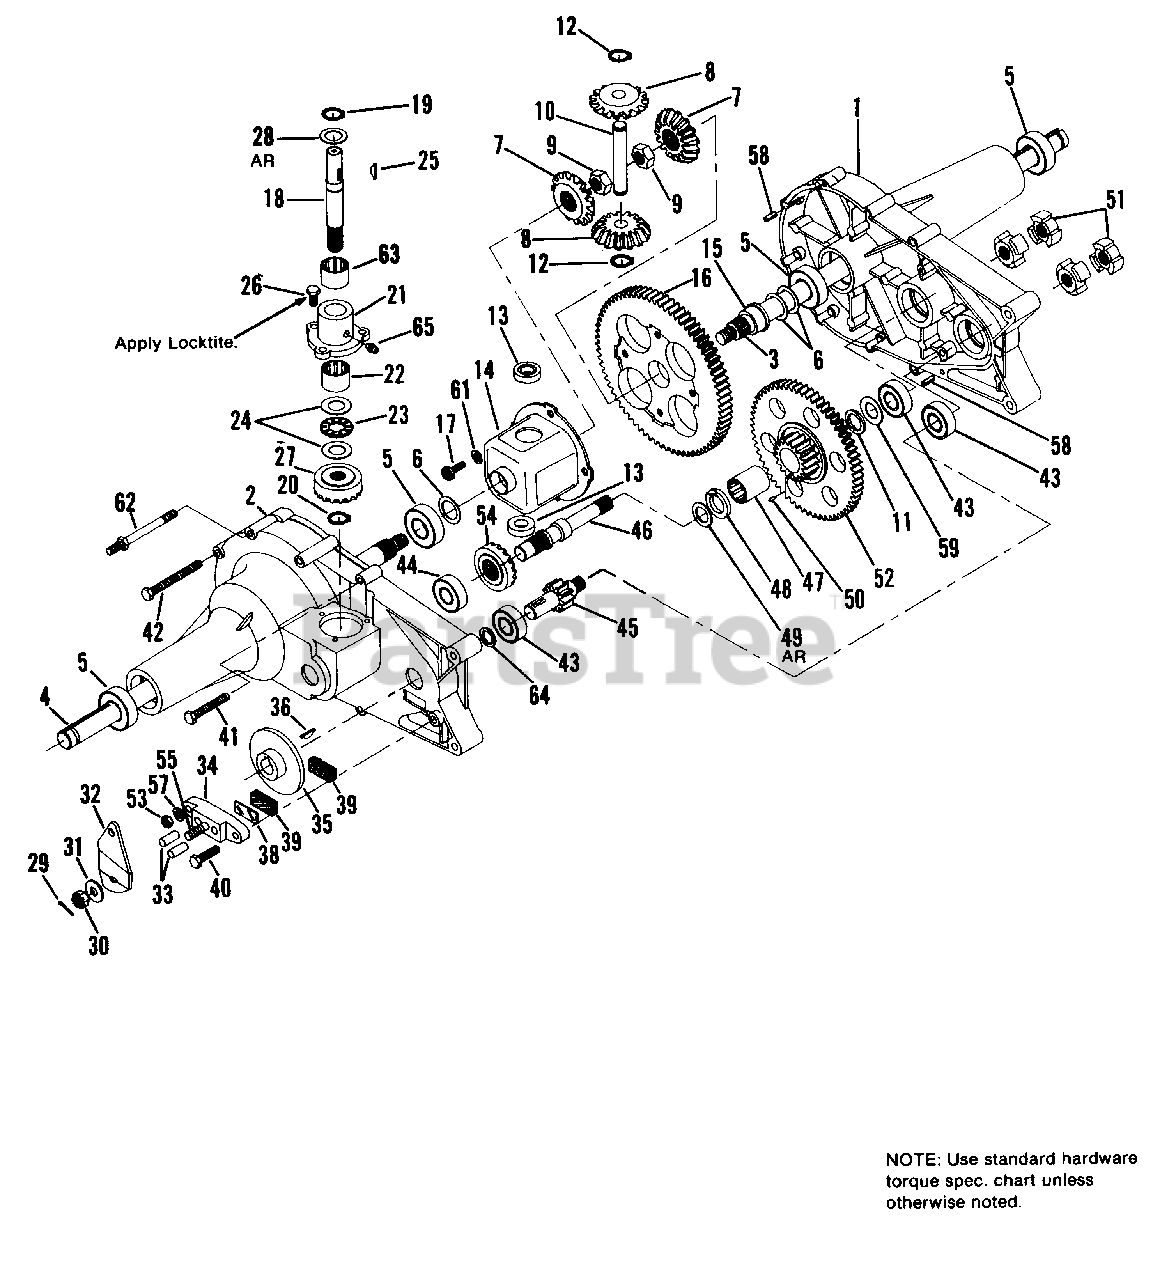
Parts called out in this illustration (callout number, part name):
1	HOUSING, Half, L.H.
2	HOUSING, Half, R.H.
3	AXLE, L.H., 3/4"
4	AXLE, R.H., 3/4"
5	BEARING, Ball
6	WASHER, Flat, 3/4 I.D. x 1-1/8 O.D. x .030 Thk.
7	GEAR, Miter
8	GEAR, Miter
9	NUT, Hex Jam w/Patch, 1/2-20
10	SHAFT, Cross
11	GREASE, Seal, Bronze
13	BEARING, Thrust
14	HOUSING ASSY., Differential
15	BEARING, Flange
16	GEAR, Differential 1/2 Tooth
17	BOLT, Torx Hd., 1/4-29 x 5/8" Lg.
18	SHAFT, Input
20	RETAINING RING, 7/16" Dia. Ext.
21	HOUSING, Input Bearing
22	BEARING, Needle
23	BEARING, Thrust
24	WASHER, Flat, 5/8 I.D. x 1-1/8 O.D. x .030 Thk.
25	KEY, Hi-Pro, 1/8 x 5/8
26	SCREW, Hex w/Patch, 1/4-20 x 3/4 Long
27	GEAR, Input Pinion, 17 Tooth
28	WASHER, Flat, .62 I.D. x 1.0 O.D. x .030 Thk.
28	WASHER, Flat, .62 I.D. x 1.125 O.D. x .060 Thk.
28	WASHER, Flat, .62 I.D. x 1.0 O.D. x .040 Thk.
29	PlN, Cotter
30	NUT, Castle, 5/16-24
31	WASHER, Flat, .343 I.D. x .88 O.D. x .062 Thk.
32	ARM, Brake Actuator
33	PIN, Brake Actuating
34	BRAKE, Yoke
35	DISC, Brake
36	KEY, Hi-Pro, 3/16 x 5/8" Dia.
38	PLATE, Puck
39	PUCK, Brake
40	SCREW, Hex w/Patch, 1/4-20 x 1.00 Lg.
41	SCREW, Hex, Self-Tap, 1/4-20 x 2.00 Lg.
42	SCREW, Hex, Self-Tap, 1/4-20 x 3.00 Lg.
43	BEARING, Ball
44	BEARING, Ball
45	SHAFT, Pinion w/11 Tooth Gear
46	SHAFT, Drive
47	BEARING, Needle
48	BRONZE THRUST BRG., 5/8 I.D. x 1-1/4 O.D. x 7/64 Thk.
49	WASHER, Flat, .62 I.D. x 1.0 O.D. x .050 Thk.
50	PIN, Dowel, 3/32 x 1/4
52	GEAR, 60 and 17 Tooth
53	NUT, Hex, 1/4-20
54	GEAR, Drive Pinion, 17 T.
55	BOLT, Square Head
57	WASHER, 1/4" Spring Lock
58	PIN, Roll, 3/16" Dia. x 1/2" Lg.
59	WASHER, Flat, .62 I.D. x 1.0 O.D. x .030 Thk.
60	SHELL DURINA-O GREASE (20 Oz.)
61	WASHER, Hd. Sprg. Lock, 1/4" (Yellow Di-Chrom)
63	BEARING, Needle (w/Seal)
64	SEAL, Grease
65	GREASE FITTING
